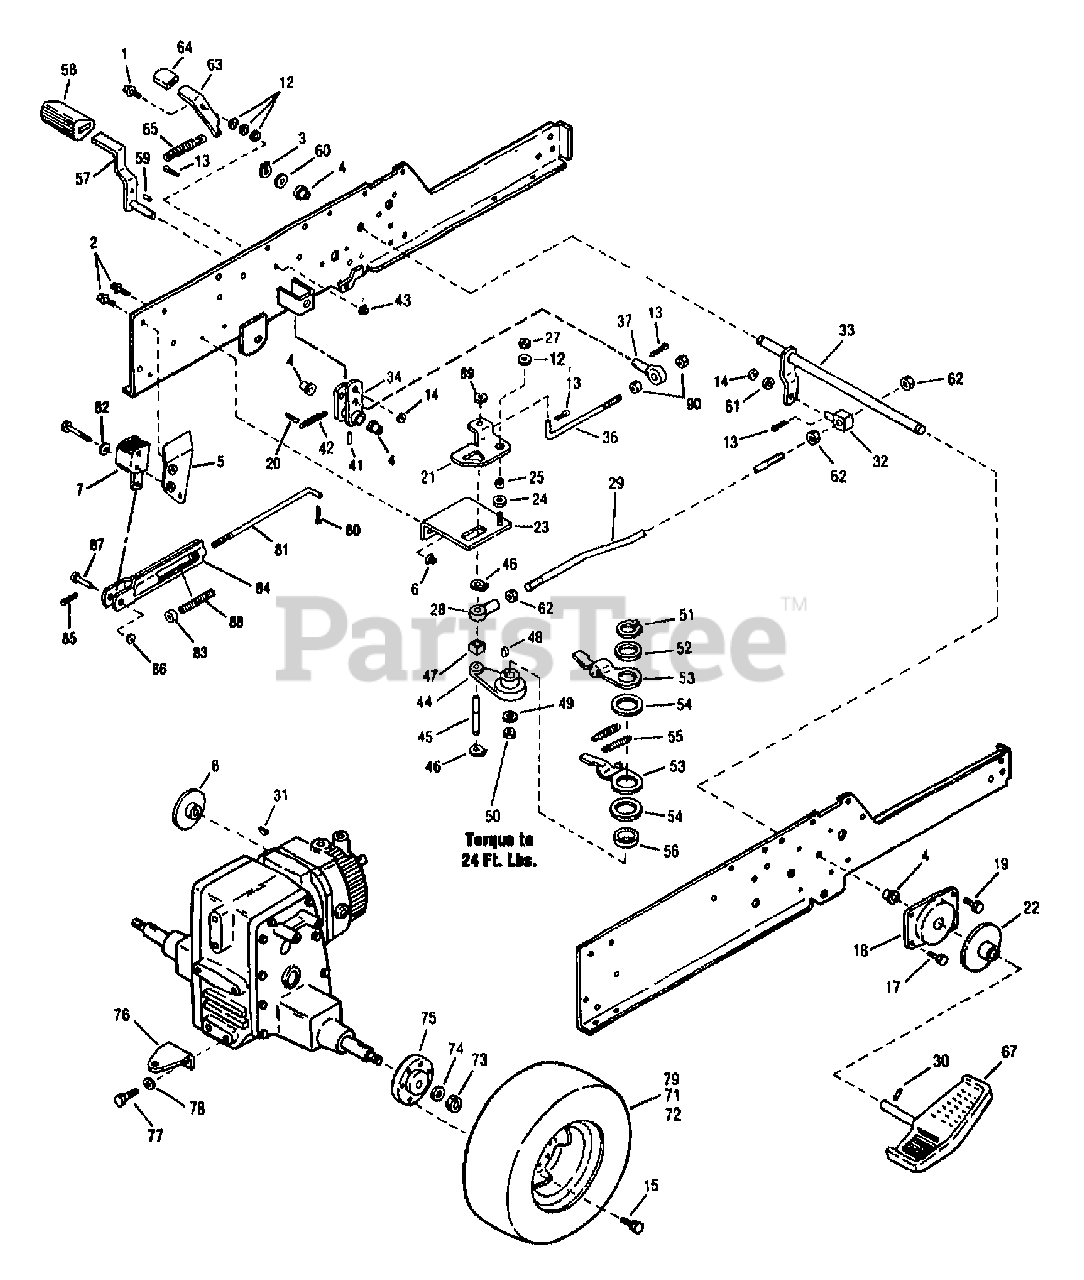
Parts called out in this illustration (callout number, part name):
1	SCR-HFLK 3/8-16X1.00 ZP
3	RING-RETAIN .625 ID
4	BEARING-FLANGE
5	BRKT-TRANS SUPPORT
6	NUT-HFLK 3/8-16 ZP
7	KIT-BRAKE
8	DISC-BRAKE {13062}
8	DISC-BRAKE {13060}
12	WASHER-FLAT 3/8 SAE
13	PIN-COTTER .09X.75 ZP
14	WASHER-FLAT 5/16 SAE
15	BOLT-HUB
18	CLUTCH
19	SCR-SEMS MACH
20	PIN-COTTER .120X1.00 ZP
21	PLATE-NEUTRAL
22	ASSM-CONTROL DISC
23	PLATE-NEUTRAL
24	WASHER-1.75X.39X.059
25	SPACER-.625X.4X.2
27	NUT-H/LK 3/8-16
28	ROD-END
29	ROD-SPEED CONTROL
30	PIN-ROLL
31	KEY-WOODRUFF .188X.75
32	SWIVEL
33	SHAFT-SPEED CONTROL
36	ROD-BRAKE CONTROL
37	SWIVEL
41	PIN-DRIVE .187X1.0
43	NUT-LOCK 3/8-16
44	ARM-SPEED CONTROL
45	PIN-CONTROL
46	RING-RET.EXT .437 ID
48	KEY-WOODRUFF 1/8 X 5/8
49	WASHER-1.06X.531X.1 ZP
50	NUT-H/LK 1/2-13
51	RING-RET
52	WASHER
54	WASHER-THRUST
55	SPRING
56	BEARING
57	PEDAL-BRAKE
58	FOOT REST
59	PIN-ROLL .188X.75
60	WASHER-1.115X.637X.06
61	WASHER-.632X.39X.0329
62	NUT-HEX/JAM 7/16-20
63	LOCK-BRAKE
64	GRIP {13060}
64	GRIP {13062}
65	SPRING
67	PEDAL-FOOT
71	TIRE-23X10.5X12
72	STEM-VALVE
73	NUT-H/LK 3/4-10
74	SPACER-1.812X.765X.179
75	HUB-WHEEL {13060}
75	HUB-WHEEL {13062}
76	HITCH-DRAWBAR
77	SCR-HH 1/2-13X1.25 G5 ZP
78	WASHER-LK .5
79	RIM-WHEEL REAR
80	PIN-COTTER .125 X .75 ZP
82	WASHER-LK .375 @ DEPL
83	NUT-SPECIAL
84	SPRING-YOKE ASSM
85	PIN-COTTER
86	WASHER-FLAT 1/4 SAE
87	PIN-CLEVIS .25X.62
90	NUT-HEX JAM 5/16-18
